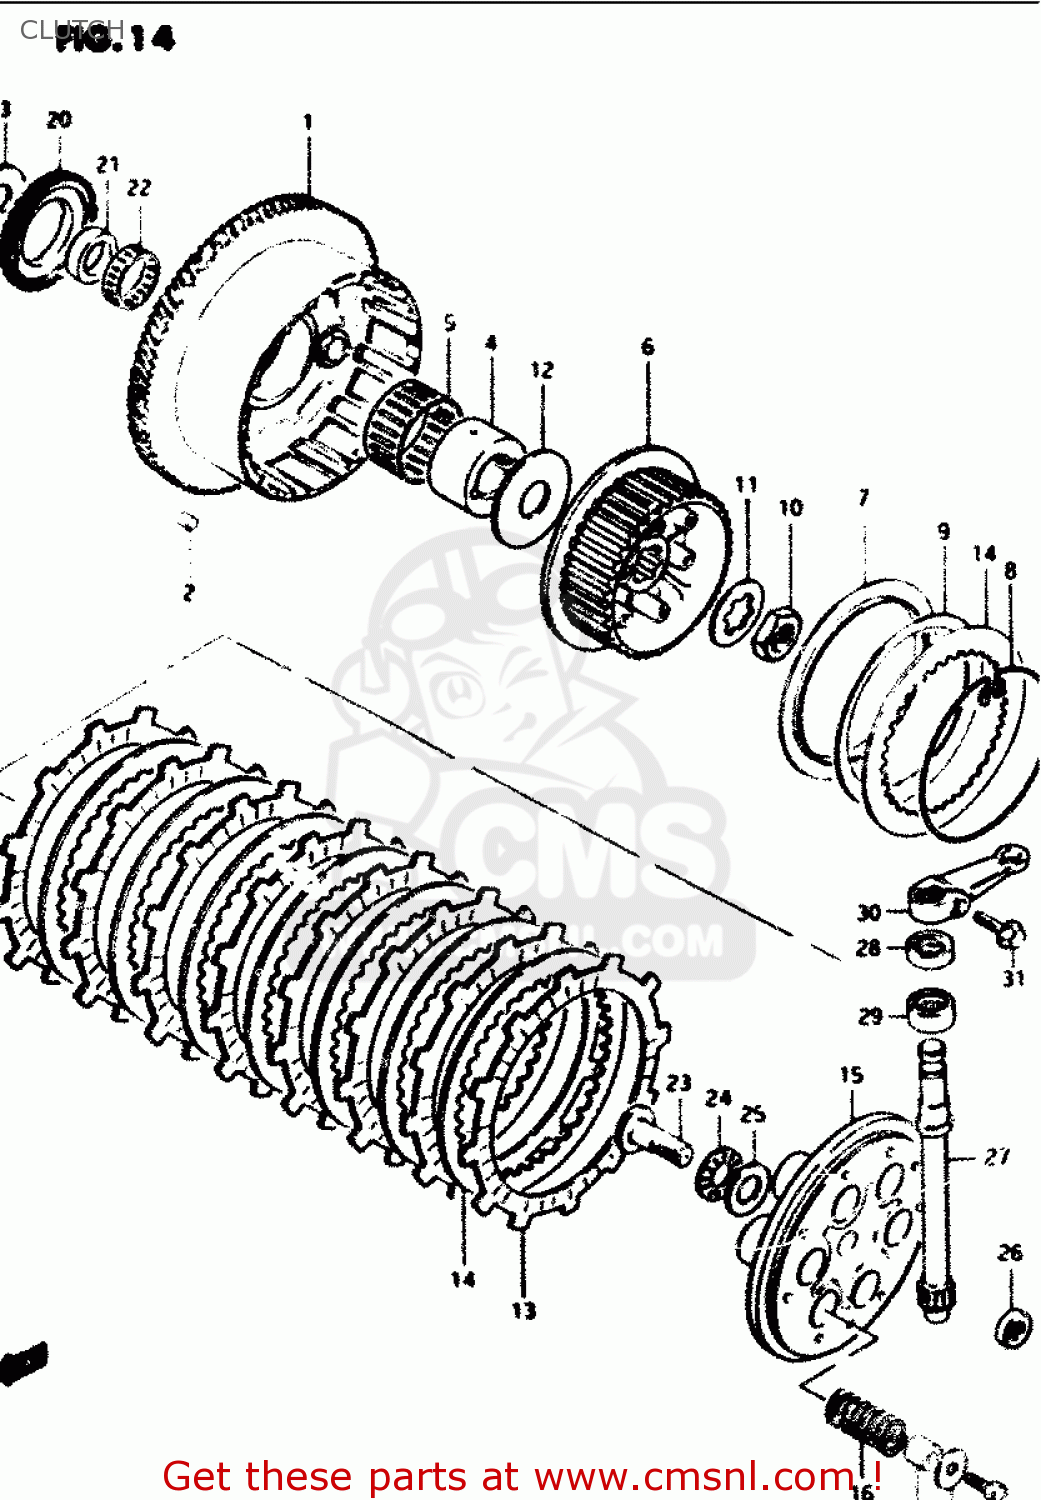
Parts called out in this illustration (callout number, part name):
1	GEAR ASSEMBLY,PRIMARY DRIVE
2	CUSHION,PRIMARY DRIVEN GEAR
3	WASHER(25X50X2.5)
4	SPACER
5	BEARING(51X56X28)
6	HUB,CLUTCH SLEEVE
7	SEAT,WAVE WASHER
8	RING,STOPPER
9	WASHER
10	NUT
11	WASHER,LOCK
12	WASHER(25X66X3.5)
13	PLATE,CLUTCH DRIVE (MCA)
14	PLATE,CLUTCH DRIVEN (NAS)
15	PLATE,CLUTCH PRESSURE
16	SPRING
17	SPACER
18	BOLT
19	WASHER
20	GEAR,ENG OIL PUMP DRIVE(NT:34)
21	SPACER,OIL PUMP DRIVE GEAR
22	BEARING(36X40X10)
23	RACK,CLUTCH RELEASE
24	BEARING(15X28X2)
25	WASHER
26	SEAL,OIL(10X16X5)
27	PINION,CLUTCH RELEASE
28	OIL SEAL
29	BEARING(15X22X12)
30	ARM,CLUTCH RELEASE
31	BOLT,REAR
